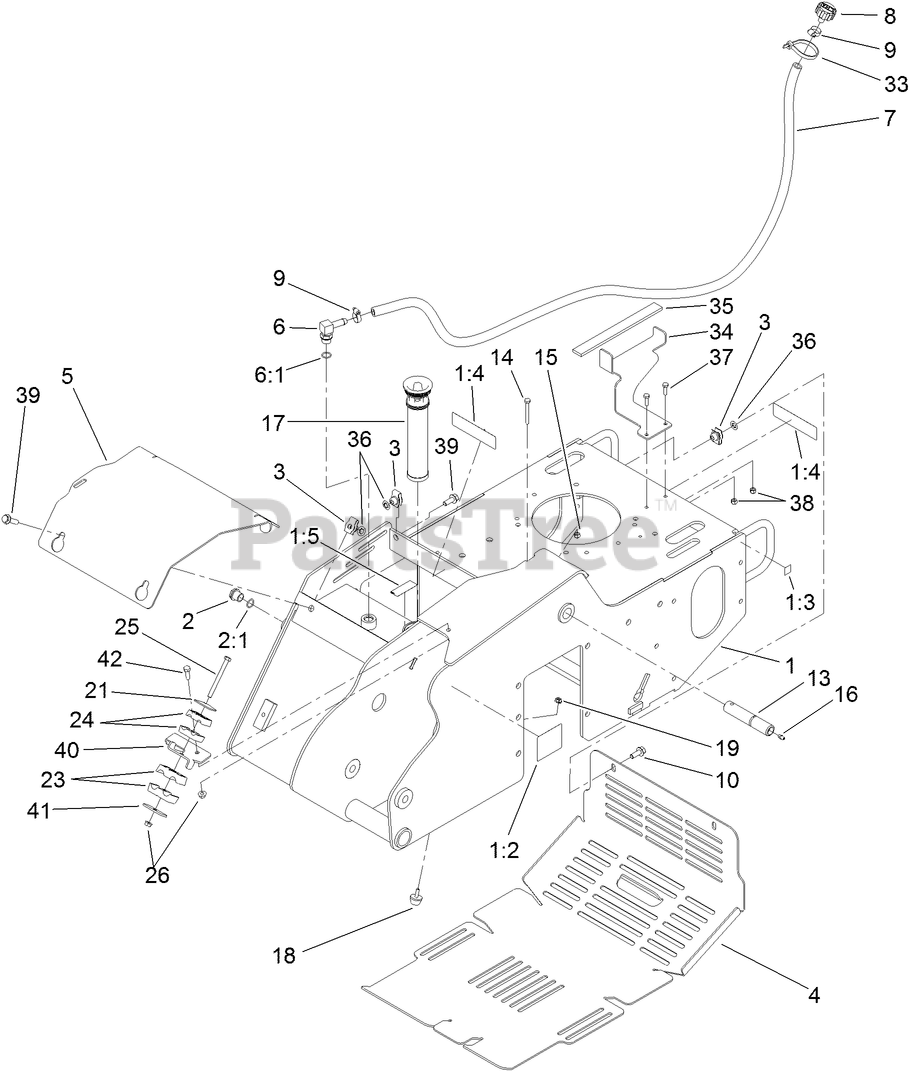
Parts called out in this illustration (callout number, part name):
1	MAIN FRAME ASM
1:2	DECAL-WARNING
1:3	DECAL-POINT, LIFT
1:4	DECAL-DANGER
1:5	DECAL-OIL, HYD
2	SIGHT GLASS ASM
2:1	O-RING
3	NUT-CLIP, U
4	COVER-REAR
5	PLATE-COVER, FRONT
6	FITTING-ELB 90
6:1	O-RING
7	HOSE-BREATHER
8	BREATHER
9	CLAMP-HOSE
10	SCREW-HHF
13	PIN-PIVOT
14	SCREW-HH
15	NUT-LOCK, NI
16	FITTING-GREASE
17	IN-TANK FILTER ASM
18	BUMPER
19	NUT-HF
21	COVERPLATE
23	CLAMP-TUBE
24	CLAMP-TUBE
25	SCREW-HH
26	NUT-HF
33	TIE-CABLE
34	BRACKET-TANK
35	PAD-FOAM
36	NUT-PUSH
37	SCREW-HH
38	NUT-LOCK, NI
39	SCREW-HHF
40	BRACKET-CLAMP
41	PLATE-CLAMP
42	SCREW-HH
